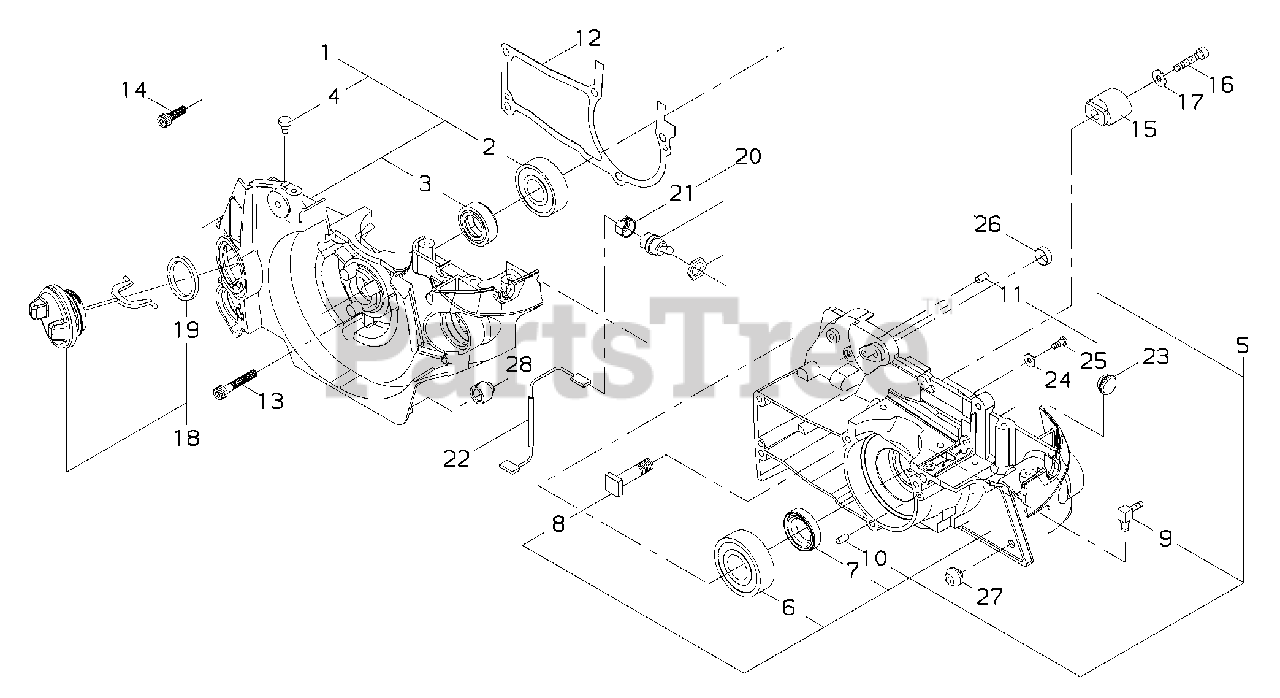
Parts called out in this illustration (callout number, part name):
1	CRANKCASE ASSY - LEFT
2	BEARING, BALL - 6201C3
3	SEAL, OIL
4	VALVE, OIL
5	CRANKCASE ASSY - RIGHT
6	BEARING, BALL - 6202C3
7	SEAL, OIL
8	STUD, GUIDE BAR
9	PULSE JOINT
10	PIN - LOCATING
11	PIN - LOCATING
12	GASKET, CRANKCASE
13	BOLT - 5X35
14	SCREW - 5X18
15	CATCHER, CHAIN
16	BOLT - 5X25
17	WASHER - 5
18	CAP ASSY
19	GASKET, CAP
20	IGNITION SWITCH ASSY
22	LEAD - IGNITION
23	PLUG
24	WASHER - 4
25	SCREW - 4X7
26	RING
27	SUPPORT C
28	SUPPORT
